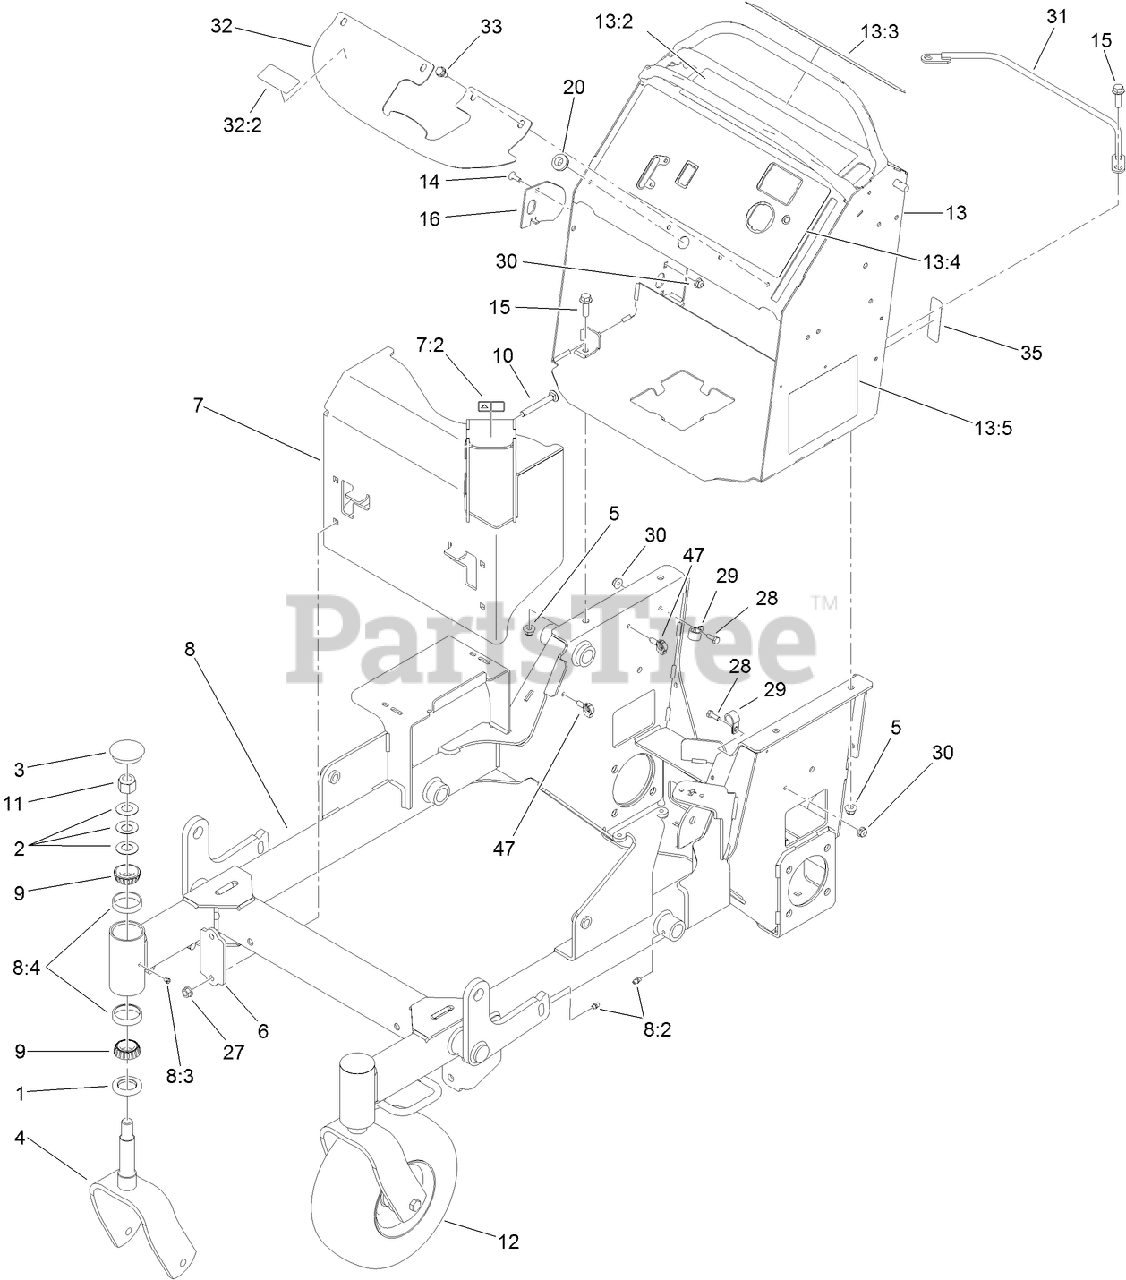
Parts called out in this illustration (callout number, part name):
1	SEAL-GREASE
2	WASHER-BELLVILLE
3	CAP-GREASE
4	FORK-CASTER
5	NUT-HF, NI
6	BRACKET-MOUNTING, GUARD
7	MUFFLER GUARD ASM
7:2	DECAL-WARNING
8	FRAME ASM
8:2	FITTING-GREASE
8:4	CUP-BEARING
9	BEARING-ROLLER, TAPERED
10	SCREW-CARR
11	NUT-LOCK, NI
12	WHEEL/TIRE AND BEARING ASM
13	CONTROL TOWER ASM
13:2	DECAL-OPC
13:3	DECAL-WARNING
13:4	DECAL-PANEL, CONTROL
13:5	DECAL-SERVICE/SPARK ARREST
14	BOLT-CARR
15	SCREW-HHF
16	PLATE-STRIKER
20	GROMMET
27	NUT-HF
28	SCREW-HH
29	CLAMP-CABLE
30	NUT-HF
31	RETAINER-CABLE
32	COVER-TANK
32:2	DECAL-FILL, FUEL
33	SCREW-HWHTF
35	DECAL-FUSE
47	CLIP-HARNESS
